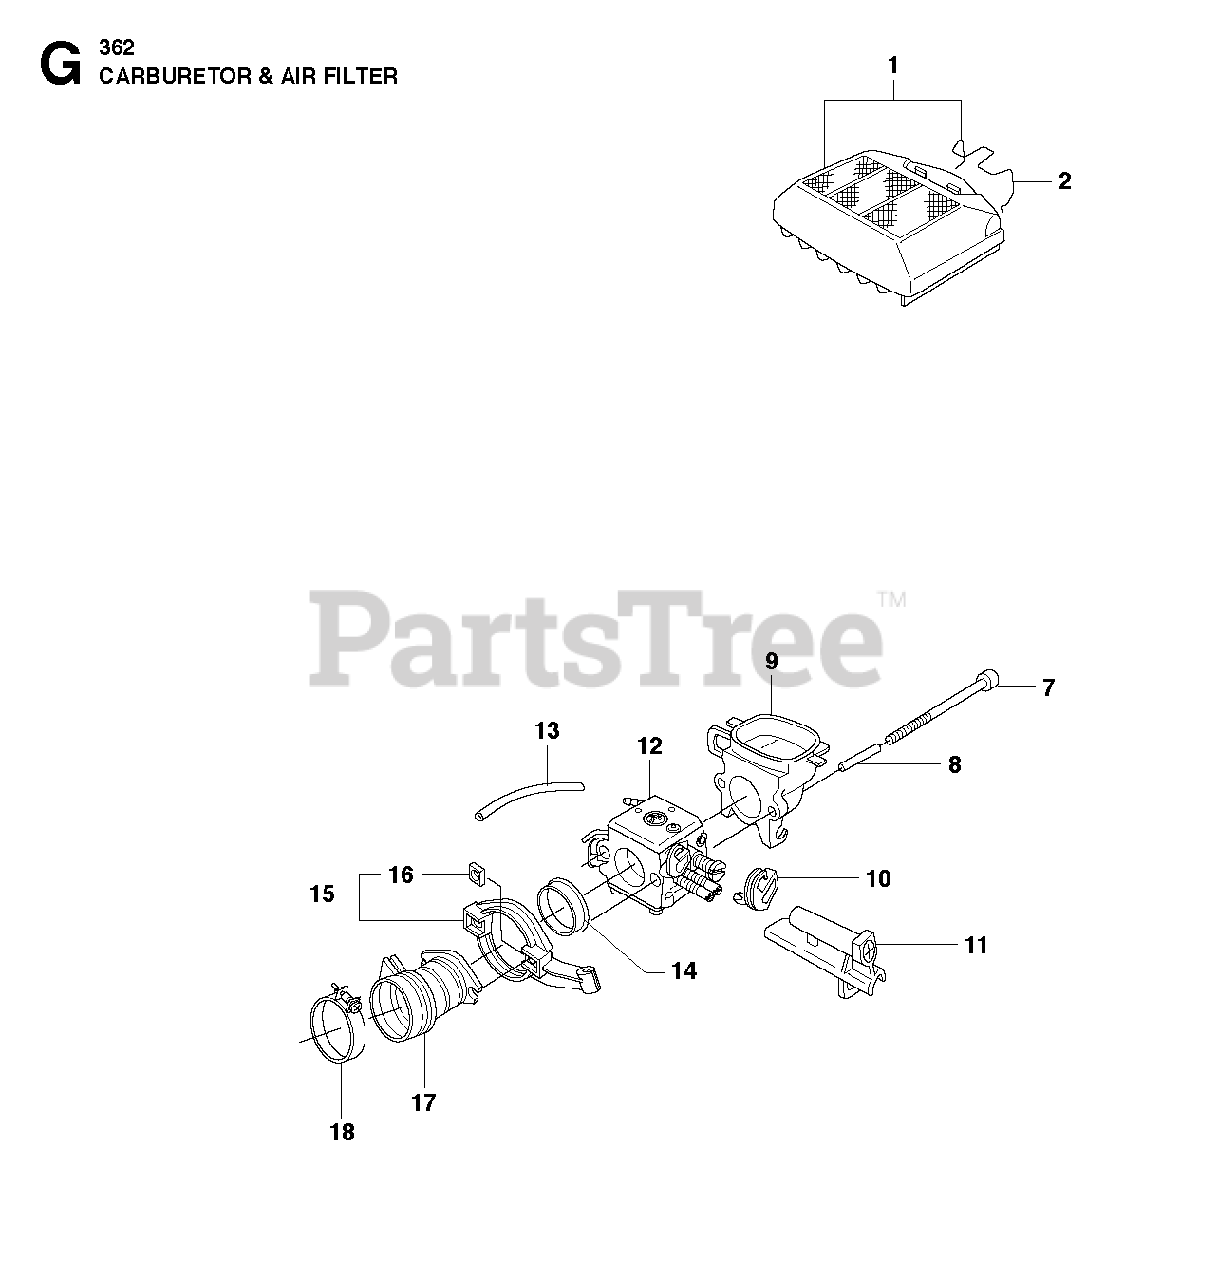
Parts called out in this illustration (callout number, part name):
1	AIR FILTER ASSY
2	AIR FILTER CLIP
9	HOLDER
12	CARBURETOR WALBRO HD-6B
16	NUT
17	INTAKE PIPE - EPA
18	CLAMP
